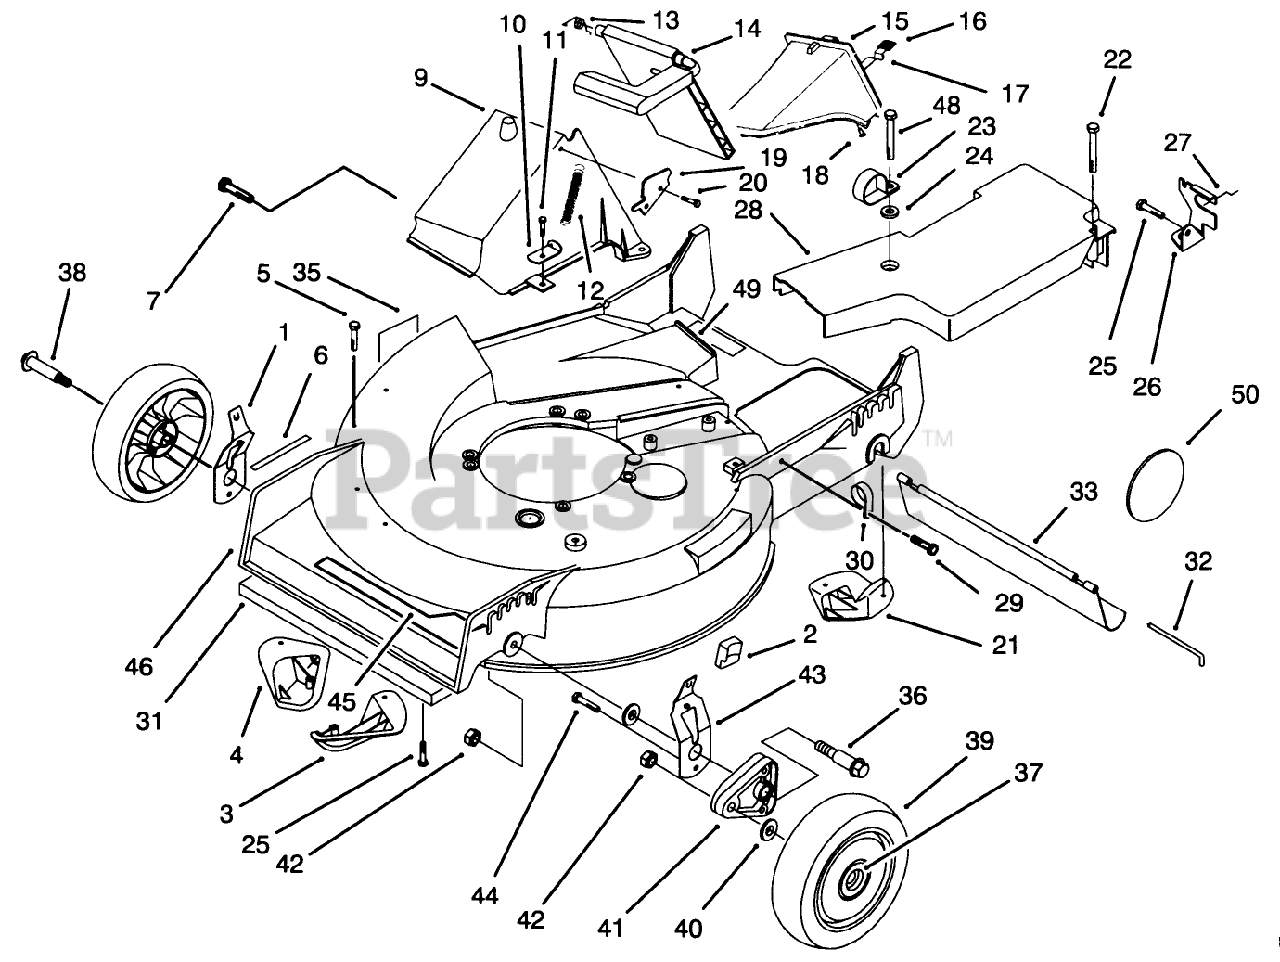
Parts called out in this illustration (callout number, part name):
1	RH SPRING ARM ASSEMBLY
2	KNOB-ARM
3	KICKER-FRONT
4	KICKER-RH
5	SCREW-PPH
7	SCREW AND WASHER ASM
9	TUNNEL-DISCHARGE
10	BRACKET-SPRING
11	SCREW-HWH
12	SPRING-DOOR
13	RETAINER-DOOR
15	DISCHARGE PLUG ASM
16	GRIP-LATCH
17	LATCH-PLUG, DISCHARGE
18	RIVET-HEAD, FLAT
19	DOOR LATCH PLATE
20	SCREW-PLASTITE
21	KICKER-REAR
22	SCREW-HWH
23	CLAMP-CABLE
24	WASHER
25	SCREW-HWHTF
27	RETAINER-CABLE
29	SCREW-HWH
30	CLAMP-CABLE
32	ROD-SHIELD
36	BOLT-SHOULDER
37	BUSHING
40	WASHER
41	ARM-PIVOT, FRONT
42	NUT-LOCK
43	LH SPRING ARM ASSEMBLY
44	SCREW-HWH
46	SP RECYCLER II DECK ASM
48	SCREW-SPECIAL
